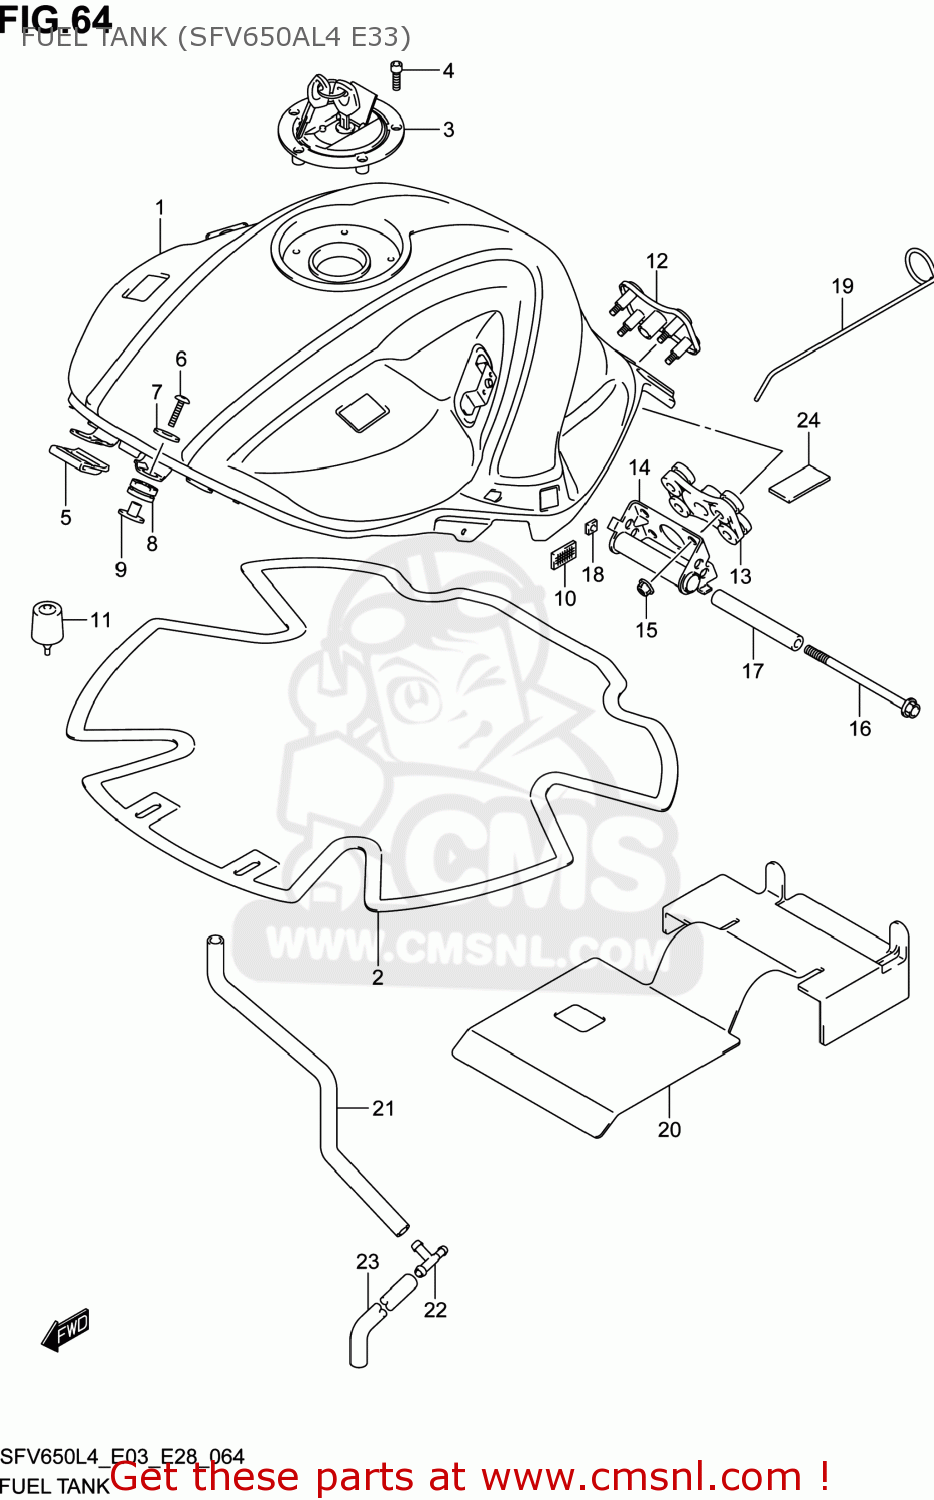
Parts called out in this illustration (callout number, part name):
1	TANK ASSY,FUEL(BLACK)
2	SHIELD,FUEL TANK HEAT
3	CAP SET,FUEL TANK
4	BOLT(5X20)
5	RUBBER,FUEL TANK FR
6	SCREW(6X25)
7	WASHER(6,5X22X1.6)
8	CUSHION,FUEL TANK FR
9	SPACER,FUEL TANK FR
10	FASTENER,FRAME COVER
11	CUSHION,FUEL TANK RR
12	BRACKET,FUEL TANK RR UP
13	CUSHION,FUEL TANK RR
14	BRACKET,FUEL TANK RR
15	NUT
16	BOLT(6X100)
17	SPACER,FUEL TANK RR
18	NUT
19	STAY,FUEL TANK
20	SHEET,HEAT SHIELD RUBBER
21	HOSE,FUEL TANK WATER DRAIN
22	3 WAY
23	HOSE,WATER DRAIN
24	PROTECTOR(30X30X3)
